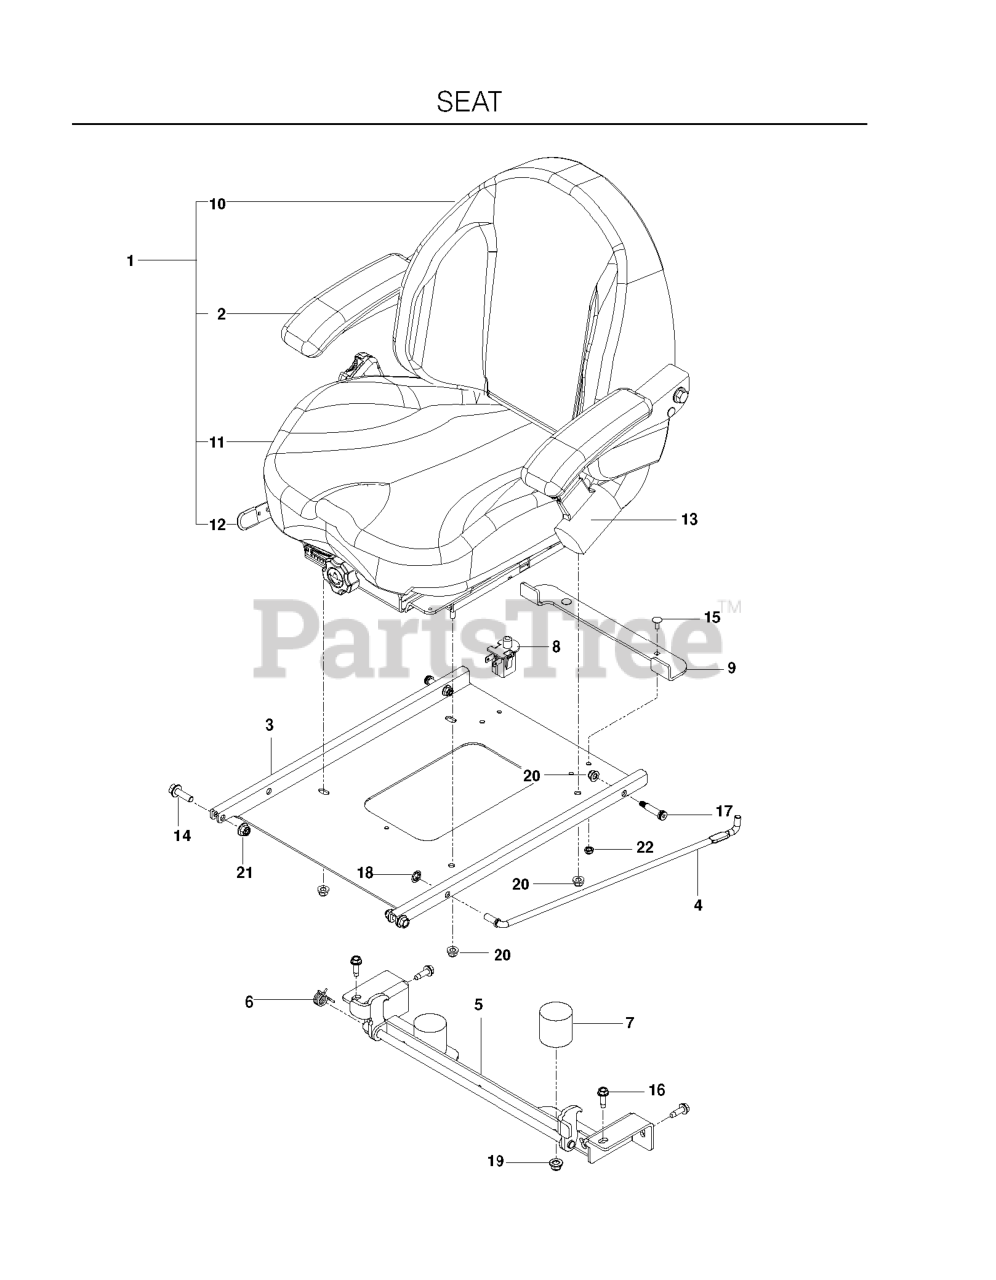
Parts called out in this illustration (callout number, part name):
1	Seat Assy
2	ARMREST, LT
3	PAN, SEAT, BLACK
5	LATCH.SEAT.BLACK
6	SPRING, TORSION
7	BUMPER, RUBBER
8	SEAT SWITCH
9	STOP, SEAT, BLK
10	COVER, BACK
11	COVER KIT, CUSHION
13	SEAT BELT, RETRACTABLE
14	HHFS 3/8-16 X 1.25 GD 5
15	RHSSNB, 1/4-20X5/8
16	RP BLT 5/16-18 X 1 THRD FORM D
17	BOLT, SHOULDER 3/8 X 1.25
18	NUT 3/8 PALNUT RTNG BLK PHOS
19	NUT 3/8-16 HEX FLG NYLOC ZD
20	5/16-18 NYLOC FLANGE NUT
21	NUT 3/8-16 HEX FLG NYLOC ZD
22	JAM NUT 1/4C (2 2 PW01)
